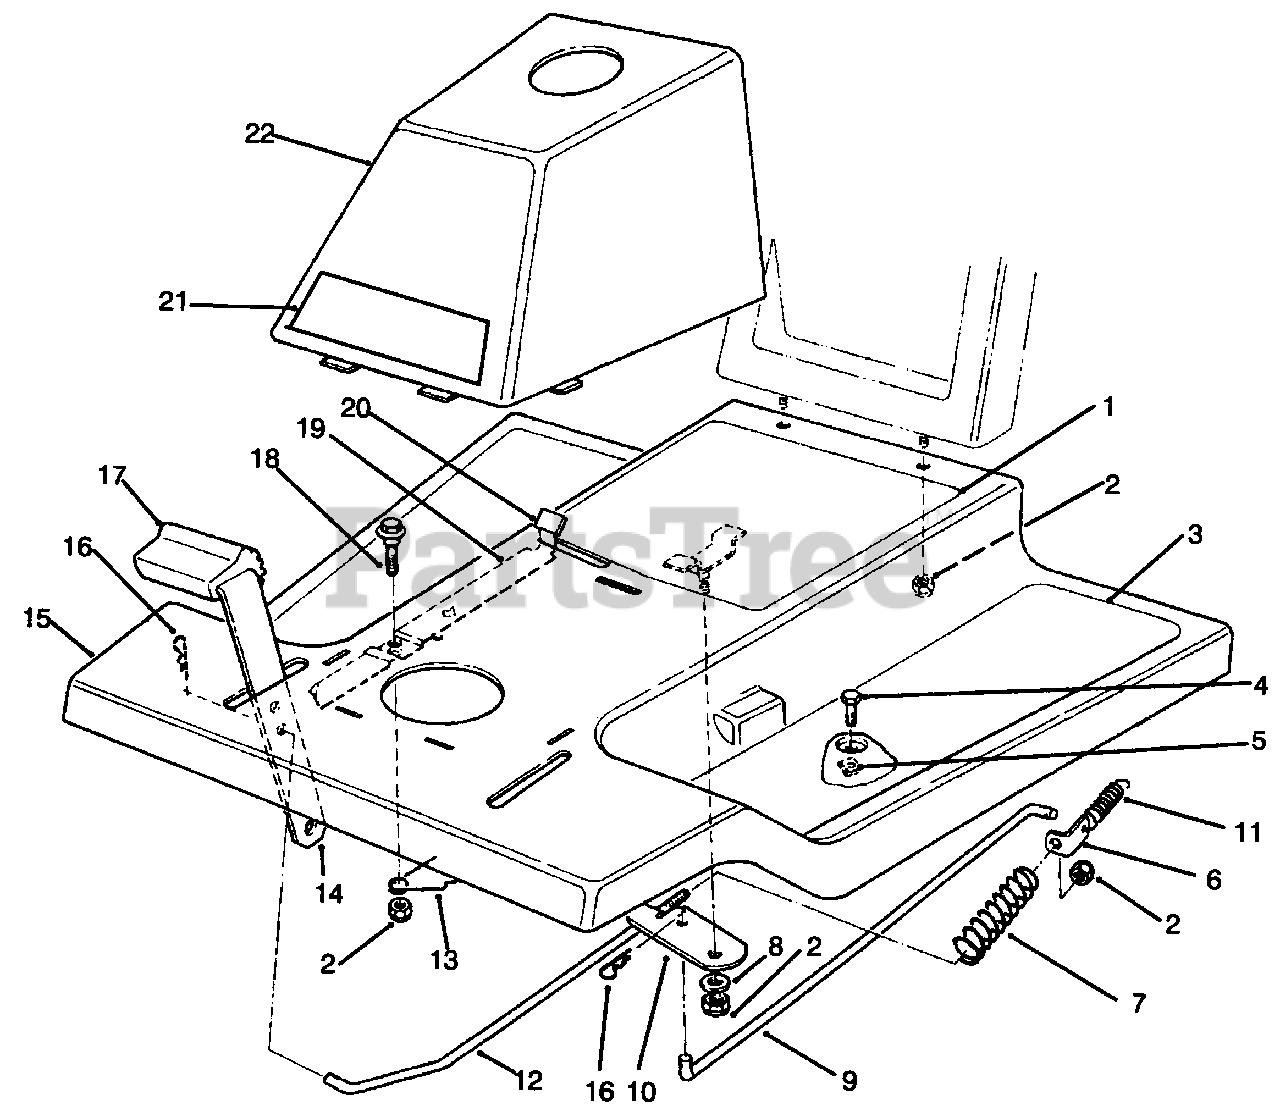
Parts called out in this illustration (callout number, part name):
1	Decal-Instruction
2	Nut-Lock
3	Tread-Foot Rest
4	Screw-Cap Hex. Hd.
5	Nut-U-Type
6	Bracket-Brake Return
7	Spring-Compression
8	Washer-Pivot
9	Rod-Brake, Transmission
10	Lever-Brake, Bellcrank
11	Spring-Extension
12	Rod-Front, Brake
13	Spring-Brake, Parking
14	Pedal-Brake & Clutch
15	Body W.A.-Front
16	Pin-Hair, Cotter
17	Pad-Pedal
18	Bolt-Shoulder
19	Lever-Brake, Parking
20	Tip-Brake, Parking
22	Tower (Incl. Ref. #21)
